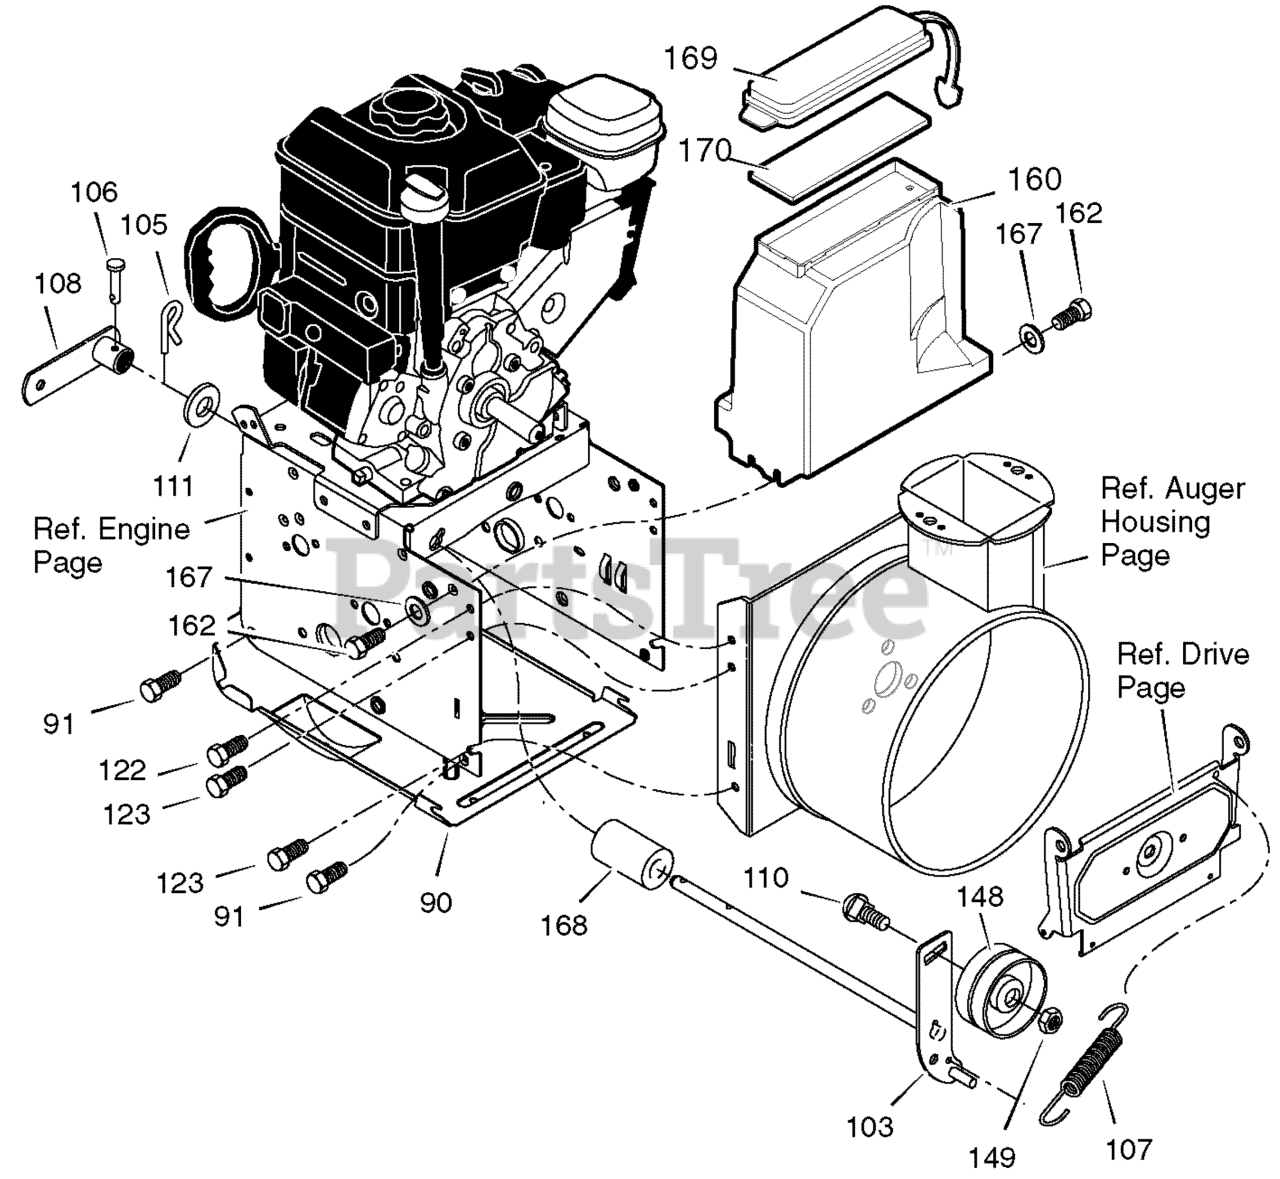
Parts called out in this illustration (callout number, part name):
90	COVER, BOTTOM
91	SCREW, 1/4-20X .63
103	IDLER ASSEMBLY, AUGER
105	PIN, HAIR .38DIAX1.64LG
106	PIN, CLEVIS 3/16" DIA
107	SPRING, TENSION
108	ASSY., SPRING ATTACH
110	BOLT, 3/8-16X1.25 CARR.
111	WASHER, FLAT
122	SCREW, TAP 5/16-18 X .50
123	SCREW, TAP 5/16-18 X .75
148	PULLEY, IDLER
149	NUT, JAM 3/8-16
160	COVER, BELT
162	SCREW, TAP
167	WASHER, FLAT
168	SPACER, AUGER BRACKET
169	LID, TOOL BOX
170	PAD, FOAM
